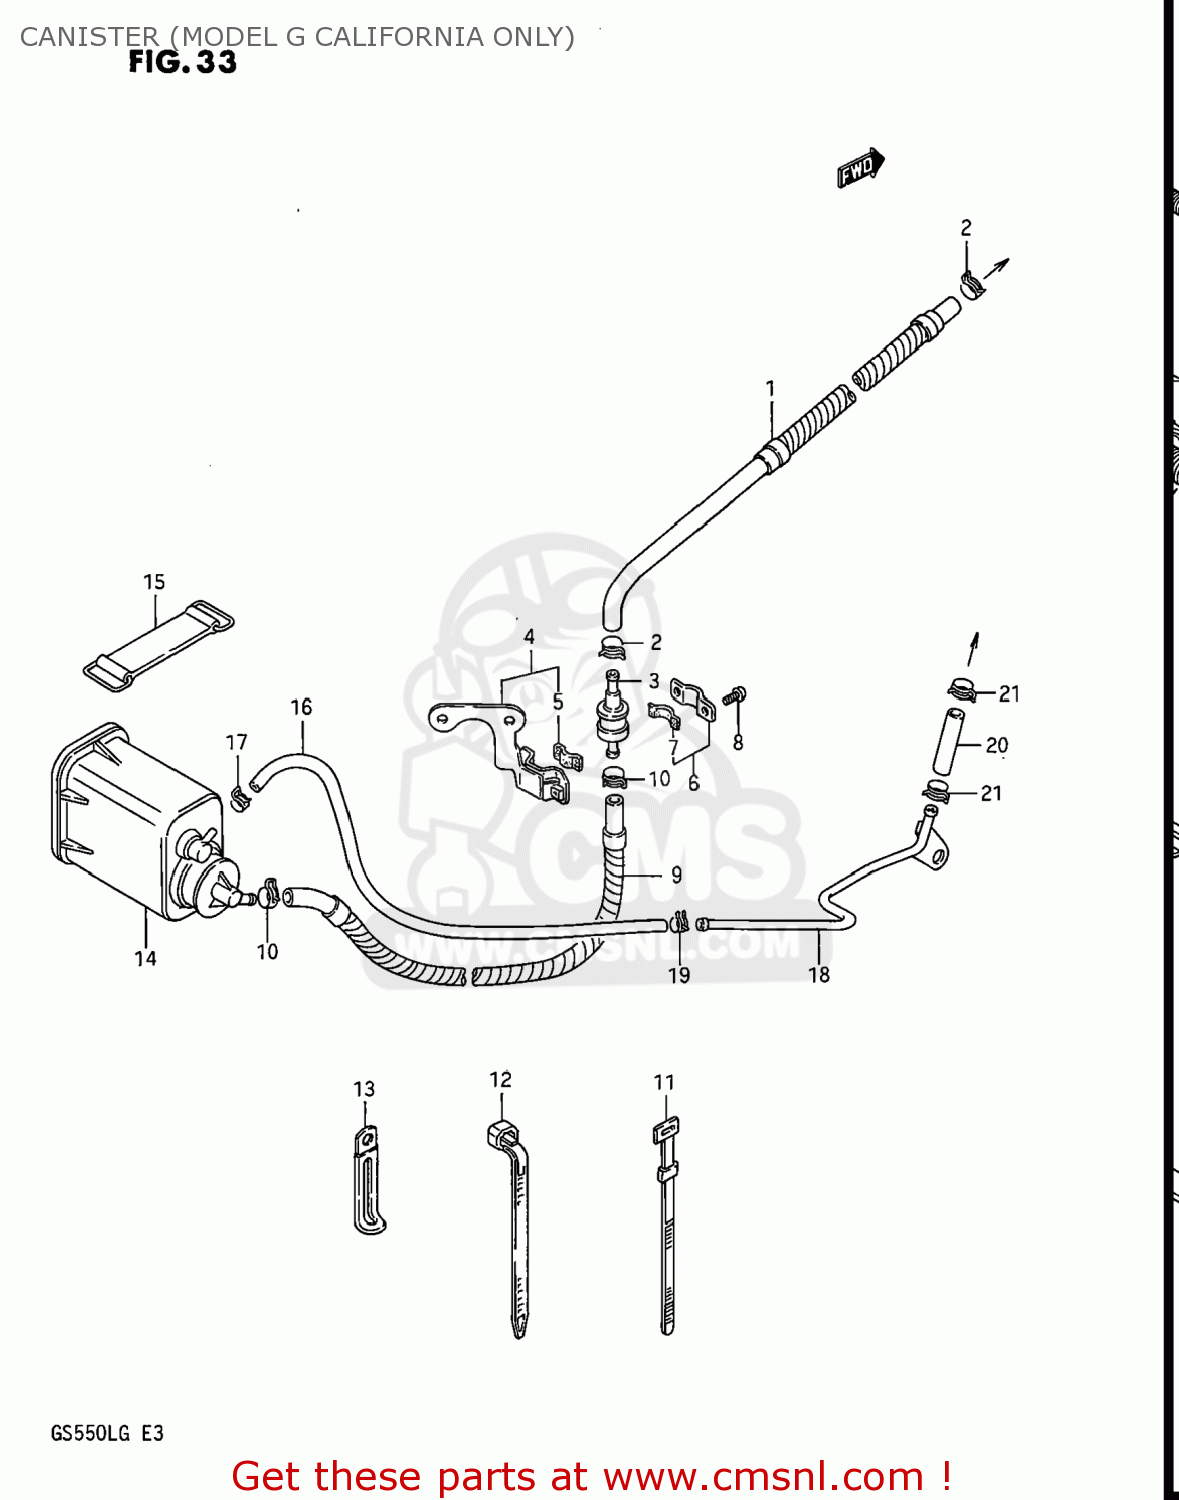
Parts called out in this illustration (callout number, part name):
1	(CA) HOSE,CHARGE NO.1
2	CLAMP
3	VALVE,FUEL TANK BREATHER
5	CUSHION
6	PLATE,FUEL TANK BREATHER NO.2
7	CUSHION
8	SCREW
9	(CA) HOSE,CHARGE NO.2
10	CLAMP
11	CLAMP
12	CLAMP(L:125)
13	CLAMP
14	(CA) CANISTER ASSEMBLY,CHARCOAL
15	BAND
16	HOSE
17	CLAMP
18	(CA) PIPE COMP,PURGE
19	CLIP
20	HOSE
21	CLAMP
